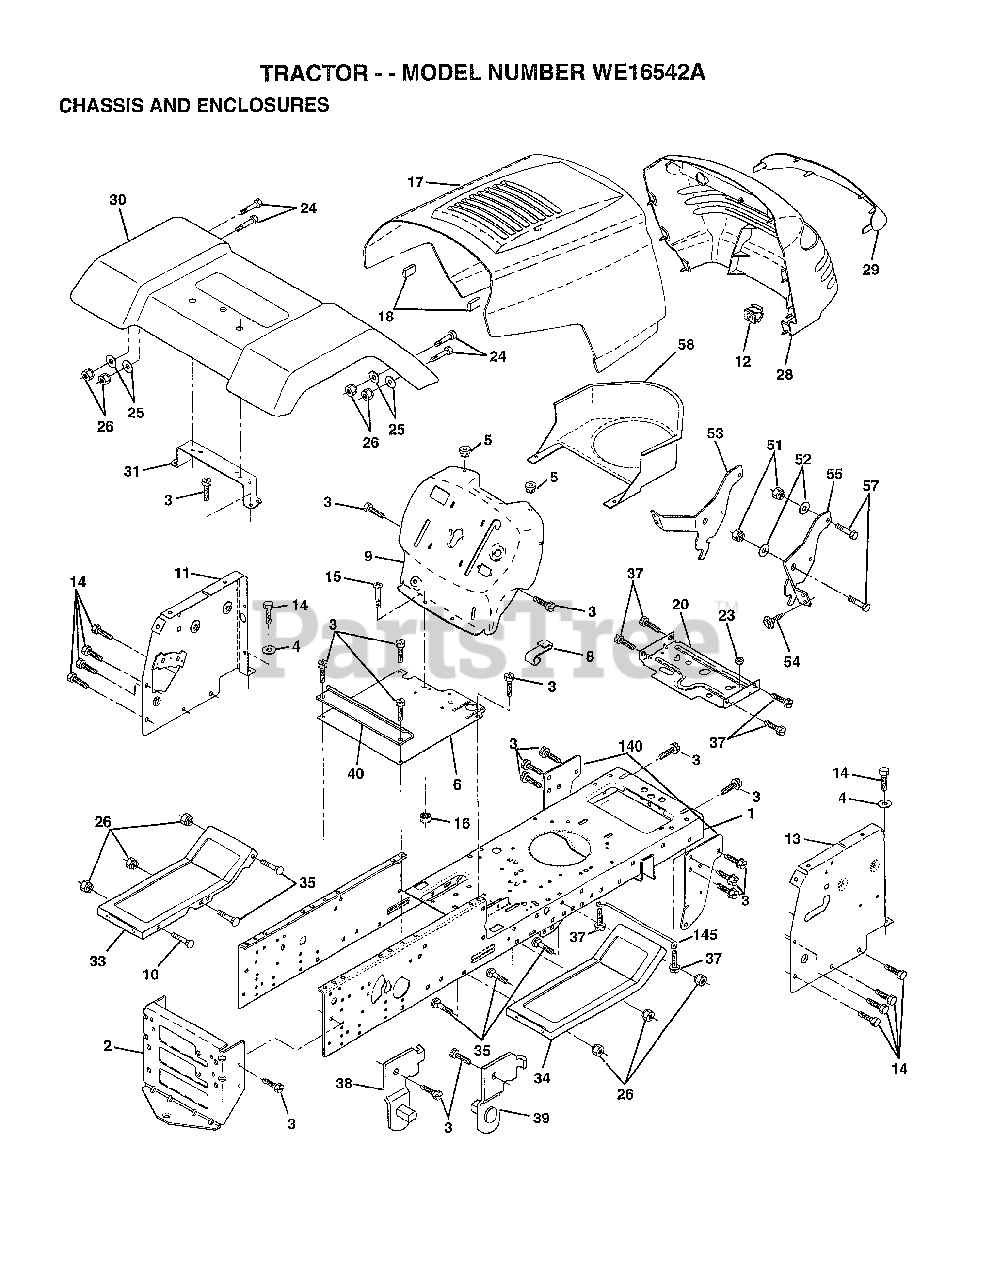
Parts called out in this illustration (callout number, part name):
3	SCREW
4	WASHER
5	BUMPER-HOOD/DASH
6	SADDLE
8	"CLIP,INSULATOR"
9	DASH SILKSCREEN
11	"PANEL-DASH,LH"
12	CLIP.TINNERMAN
14	SCREW LT
15	SCREW
17	HOOD.STEEL.ASSY
20	"PLATE-MTG,BATT/FU"
24	BOLT
25	WASHER
26	NUT
28	GRILLE-MS428
29	LENS GRILLE
31	BRACKET SUPT FEND
33	FOOTREST.LH.LT/GT
34	FOOTREST.RH.LT/GT
35	BOLT
37	SCREW LT
38	BRACKET ASM LH
39	BRACKET ASM RH
40	SPACER FENDER LT
51	NUT
52	WASHER
53	BRACKET.GRILLE.LH
54	SCREW.HEX.WS.HD
55	BRACKET.GRILLE.RH
58	AIR DUCT
140	BRKT SUSPENSION
145	"ROD POVOT,CHASSIS"
